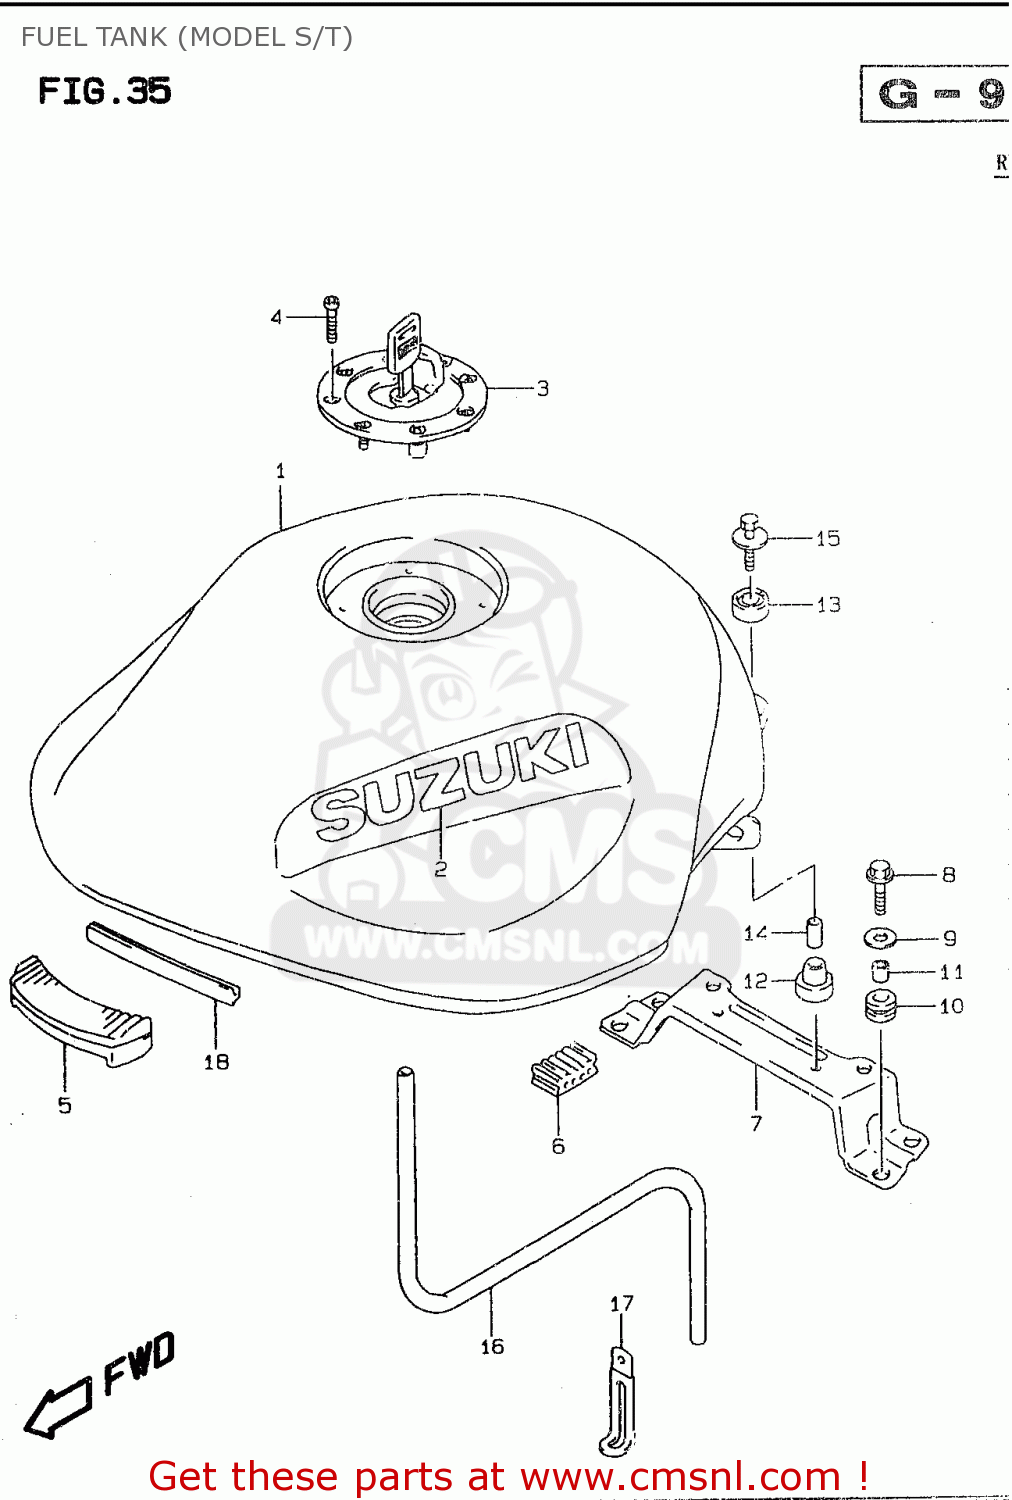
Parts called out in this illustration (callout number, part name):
1	TANK ASSEMBLY,FUEL
2	EMBLEM,FUEL TANK
3	CAP SET,FUEL TANK
4	BOLT(5X20)
5	CUSHION,FUEL TANK FR
6	CUSHION,SEAT(40X20X15)
7	BRACKET,FUEL TANK RR
8	BOLT
9	WASHER(6.5X18X1)
10	CUSHION
11	WASHER
12	CUSHION
13	CUSHION
14	SPACER(6.5X9X18)
15	BOLT(6X30)
16	HOSE(7X10.2X2000)
17	CLAMP(L:97)
18	MOLDING,FUEL TANK
